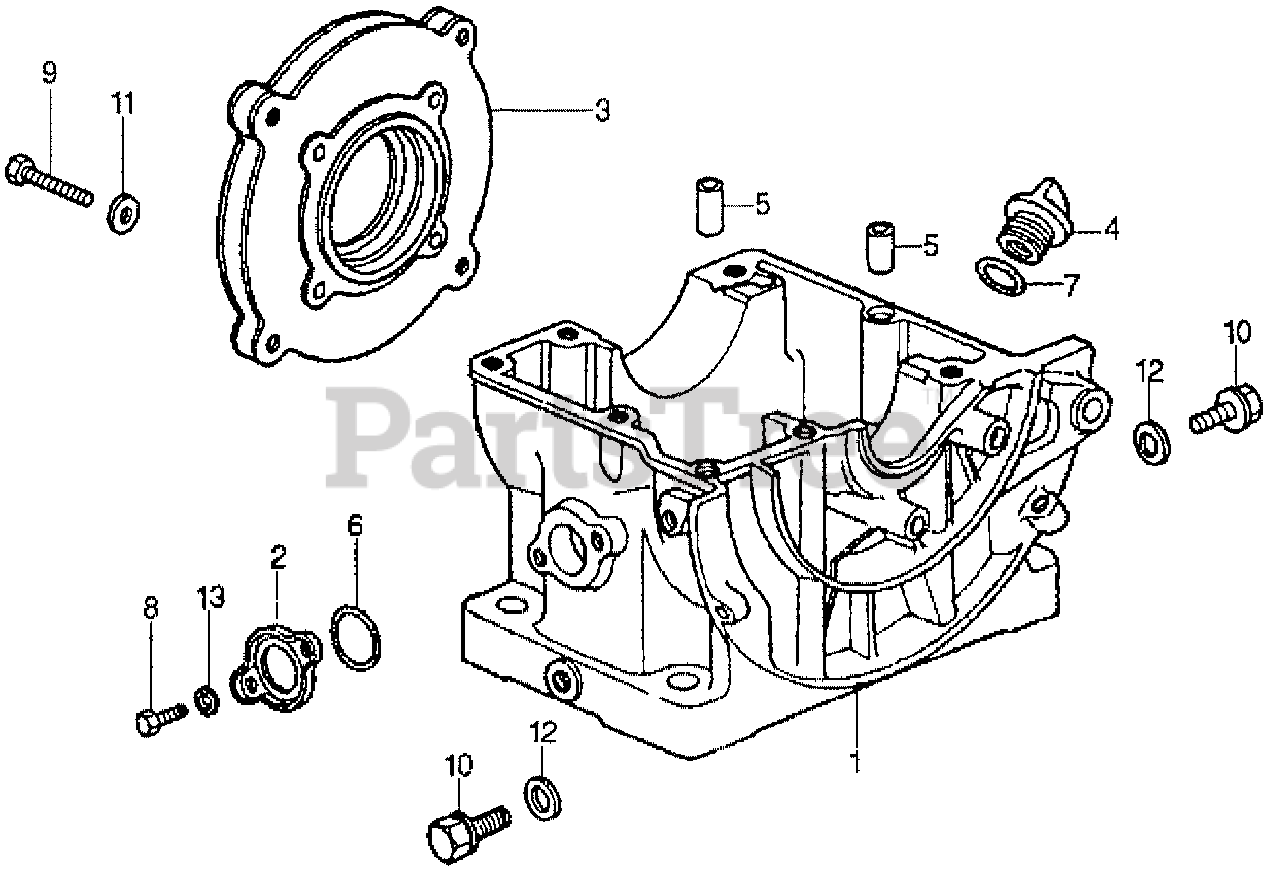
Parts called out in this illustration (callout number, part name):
2	COVER, OIL PAN
5	PIN, KNOCK (8.5X11) (NOT AVAILABLE)
6	O-RING (27X2.0)
7	O-RING (26X2.7)
8	BOLT, HEX. (6X12)
10	BOLT, DRAIN PLUG (12MM)
12	WASHER, DRAIN PLUG (12MM)
13	WASHER, SPRING (6MM)
